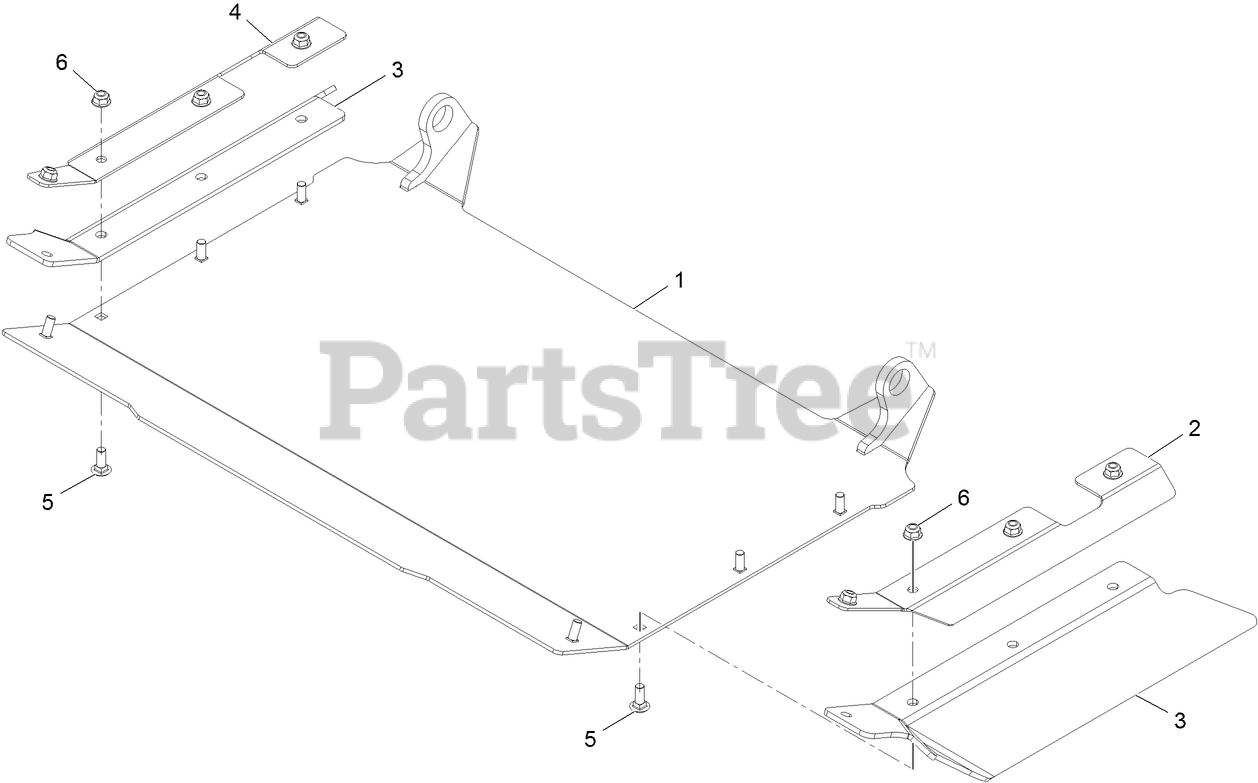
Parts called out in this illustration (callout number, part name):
1	Discharge-Tunnel 72 [black]
2	Bracket-Flap, LH
3	FLAP-RUBBER
4	Discharge-Tunnel 72 [black]
5	SCREW-CARR
6	NUT-HF, NI
